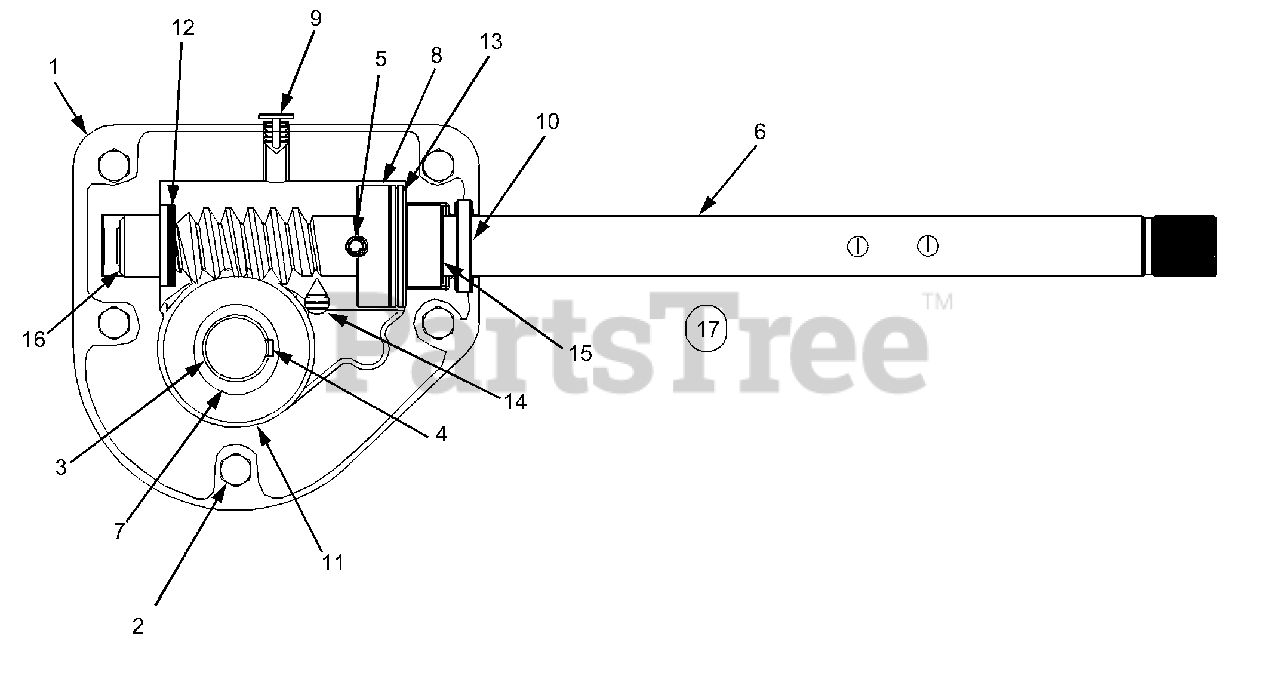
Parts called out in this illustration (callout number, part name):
1	Housing-R.H.
2	Hex Screw 1/4-20 x .75
3	Spiral Axle 22"
4	Key
5	Pin-Spiral
6	Shaft-Worm
7	Gear-Worm
8	Collar-Thrust
10	Seal-Oil
11	Washer-Flat
12	Washer-Flat
13	Washer-Flat
14	Grease
15	Bearing-Flange
16	Bearing-Flange
17	Ass'y. Complete 22"
